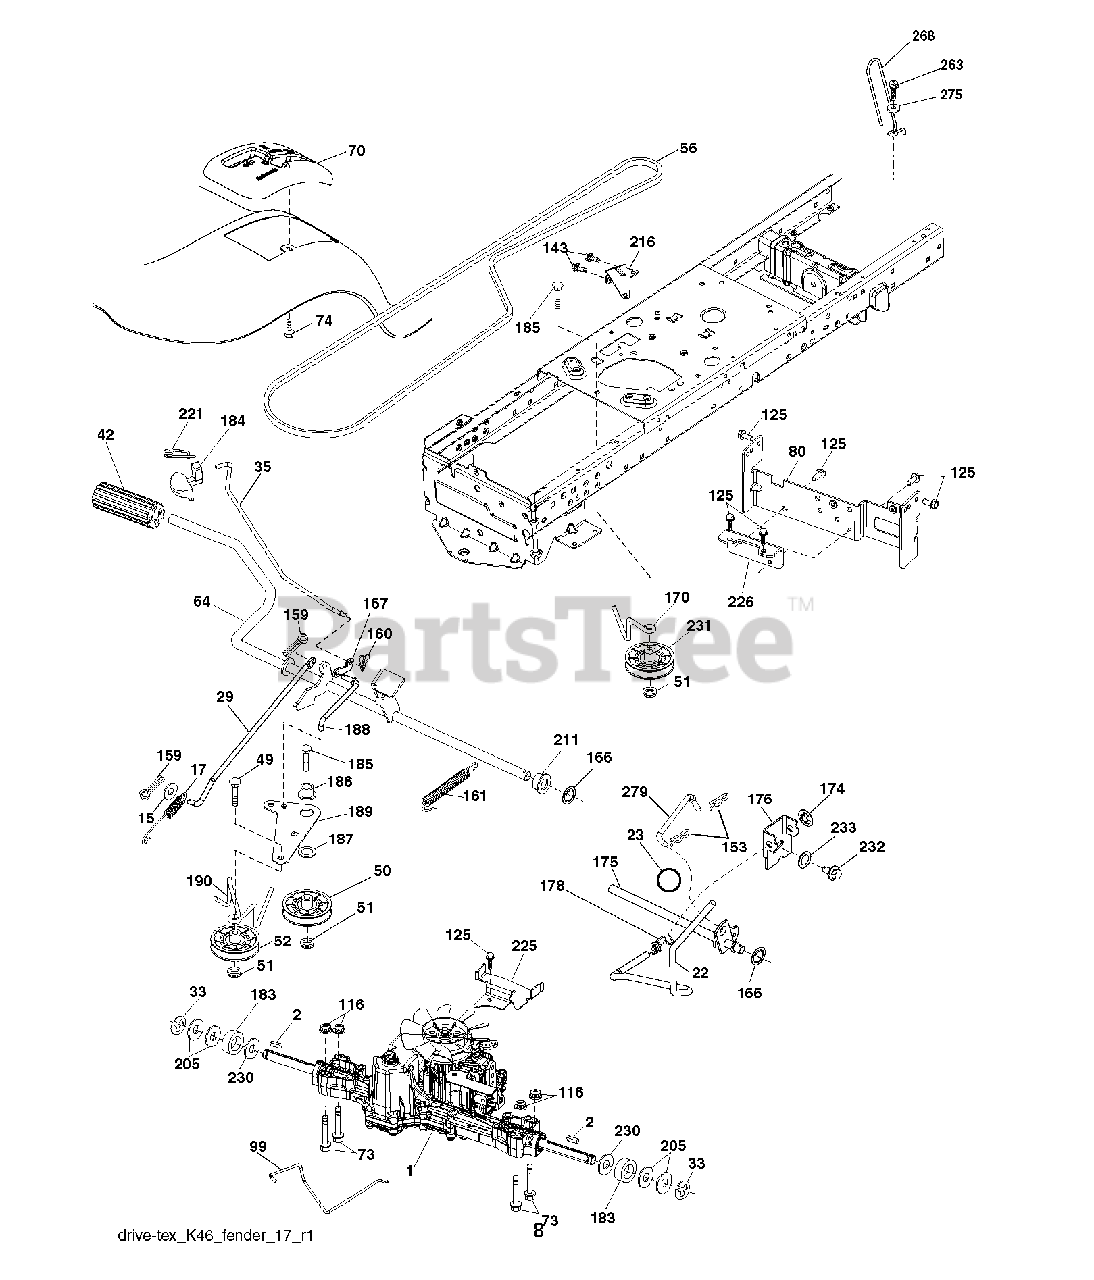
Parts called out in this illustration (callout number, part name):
2	SQUARE KEY
17	SPRING.BRAKE.K46.GREEN
22	ROD.SHIFT.FENDER.TLT.2006
23	KNOB.DUCKHEAD.1/2
29	ROD.BRAKE.K46
33	E-RING LT
35	ROD, BRAKE, PARK
42	PEDAL COVER T
49	BOLT
50	IDLER.FLAT.910.OFFSET
51	NUT LOCK FLG 3/8-16 UNC
52	IDLER.V-GROOVE.910.OFFSET
64	SHAFT.ASM.PEDAL.BRAKE.
70	CONSOLE.SHIFT.STL.HYD.BLACK
73	BOLT HEX 5/16-18 GR 5
74	SCREW.HI-LO.CONSOLE
80	STRAP TORQUE
99	ROD.SPRING.BYPASS.K46.LT.Z
116	NUT LOCK HEX FLANGE 5/16-18
125	SCREW
153	RETAINER M
159	COTTER PIN
160	RETAINER CLIP
161	SPRING, RETURN LT
166	NUT.PUSH.625
167	LATCH.BRAKE.SPRING
170	KEEPER.CENTER SPAN.1.688
174	NUT.PUSH.500.2006
175	SHAFT.ASM.SHFT.T2.TLT
176	ARM.CLEVIS.ROD.SHIFT
178	SPRING.SHIFT.GT2006
183	SPACER AXLE
184	HANDLE PARKING BRAKE
186	SPACER.RETAINER
187	WASHER 12/32X2X10GA
188	LINK.CLUTCH.GROUND.DRIVE
189	BELLCRANK.GROUND.DRIVE.TEX.
190	KEEPER.BELLCRANK.DRIVE
211	BUSHING.SHAFT.BRAKE.HAND
216	BRACKET.PULLEY.IDLER.W/TEX
221	RETAINER.SPRING.CLIP.H
225	KEEPER.BELT.TRANSAXLE.K46
226	BRACKET.MOUNT.TORQUE.K46.TLT
230	WASHER.HARDENED
231	IDLER.V-GROOVE.1.688.OFFSET
232	BOLT FIN HEX 7/16-14 X 1
233	WASHER SERRATED
263	SCREW, 3/8-16X3/4
275	WASHER
279	LINK.SHIFT.
